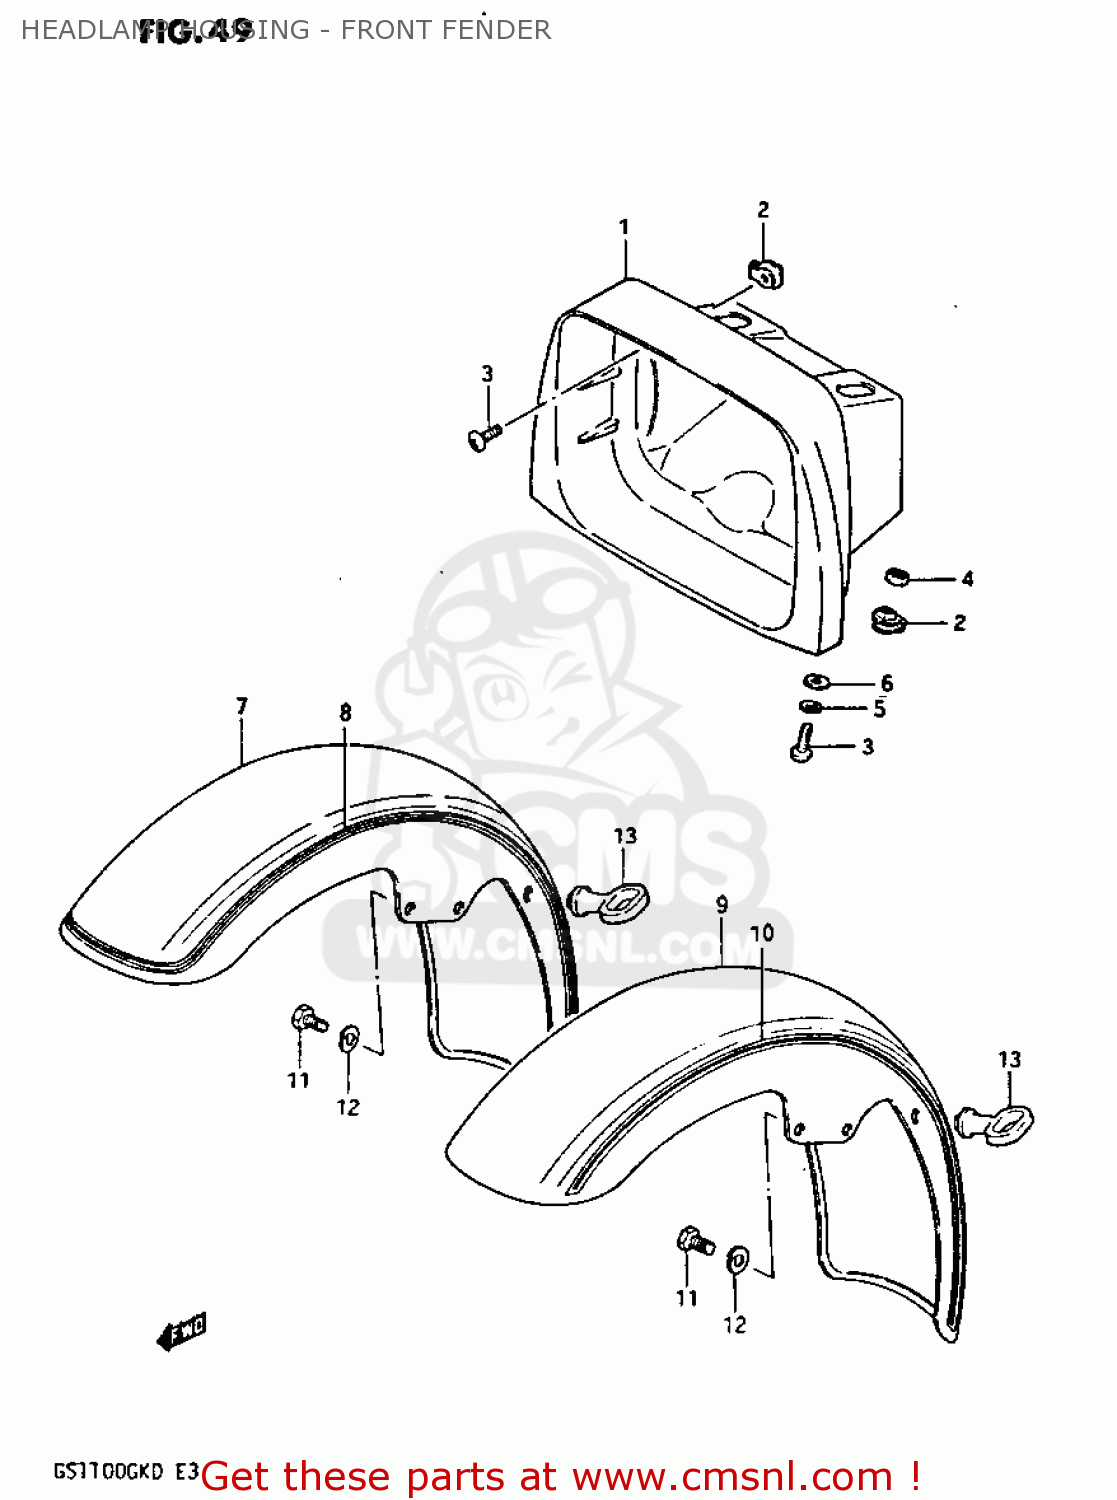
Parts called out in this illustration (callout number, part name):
1	HOUSING,HEADLAMP
2	PLATE
3	(5X20) CROSS SCREW
4	NUT
5	LOCK WASHER
6	WASHER
7	FENDER,FRONT
8	TAPE,FRONT FENDER
9	FENDER,FRONT
10	TAPE,FRONT FENDER
11	BOLT
12	LOCK WASHER
13	GUIDE,CABLE
